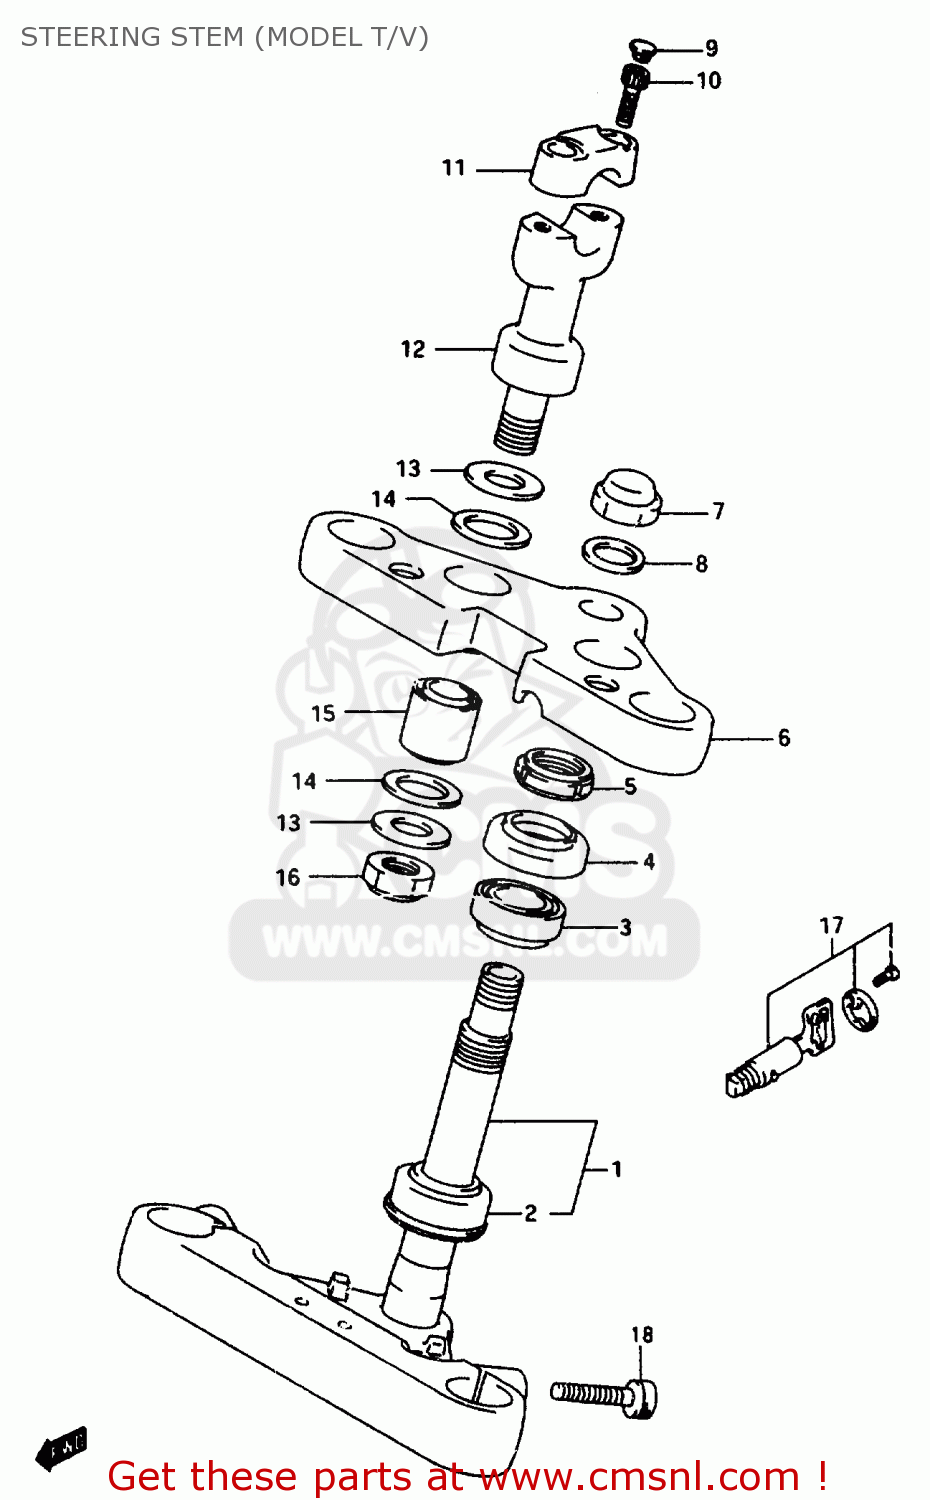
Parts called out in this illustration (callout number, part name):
1	STEM,STEERING
2	BEARING(30X55X17)
3	BEARING(25X47X15)
4	SEAL,STEERING UPR DUST
5	NUT,STEERING STEM(25X44X10)
6	HEAD,STEERING STEM
7	NUT,CAP
8	WASHER(22.5X32X1.6)
9	CAP(OD:14.5)
10	BOLT
11	HOLDER,HANDLE UPR
12	HOLDER,HANDLE
13	WASHER
14	SEAT,RUBBER
15	CUSHION
16	NUT
17	LOCK SET,STEERING
18	BOLT
19	NUT
20	PIN
21	LOCK SET,STEERING
22	CASE,STEERING KEY
23	LABEL,STEERING LOCK
